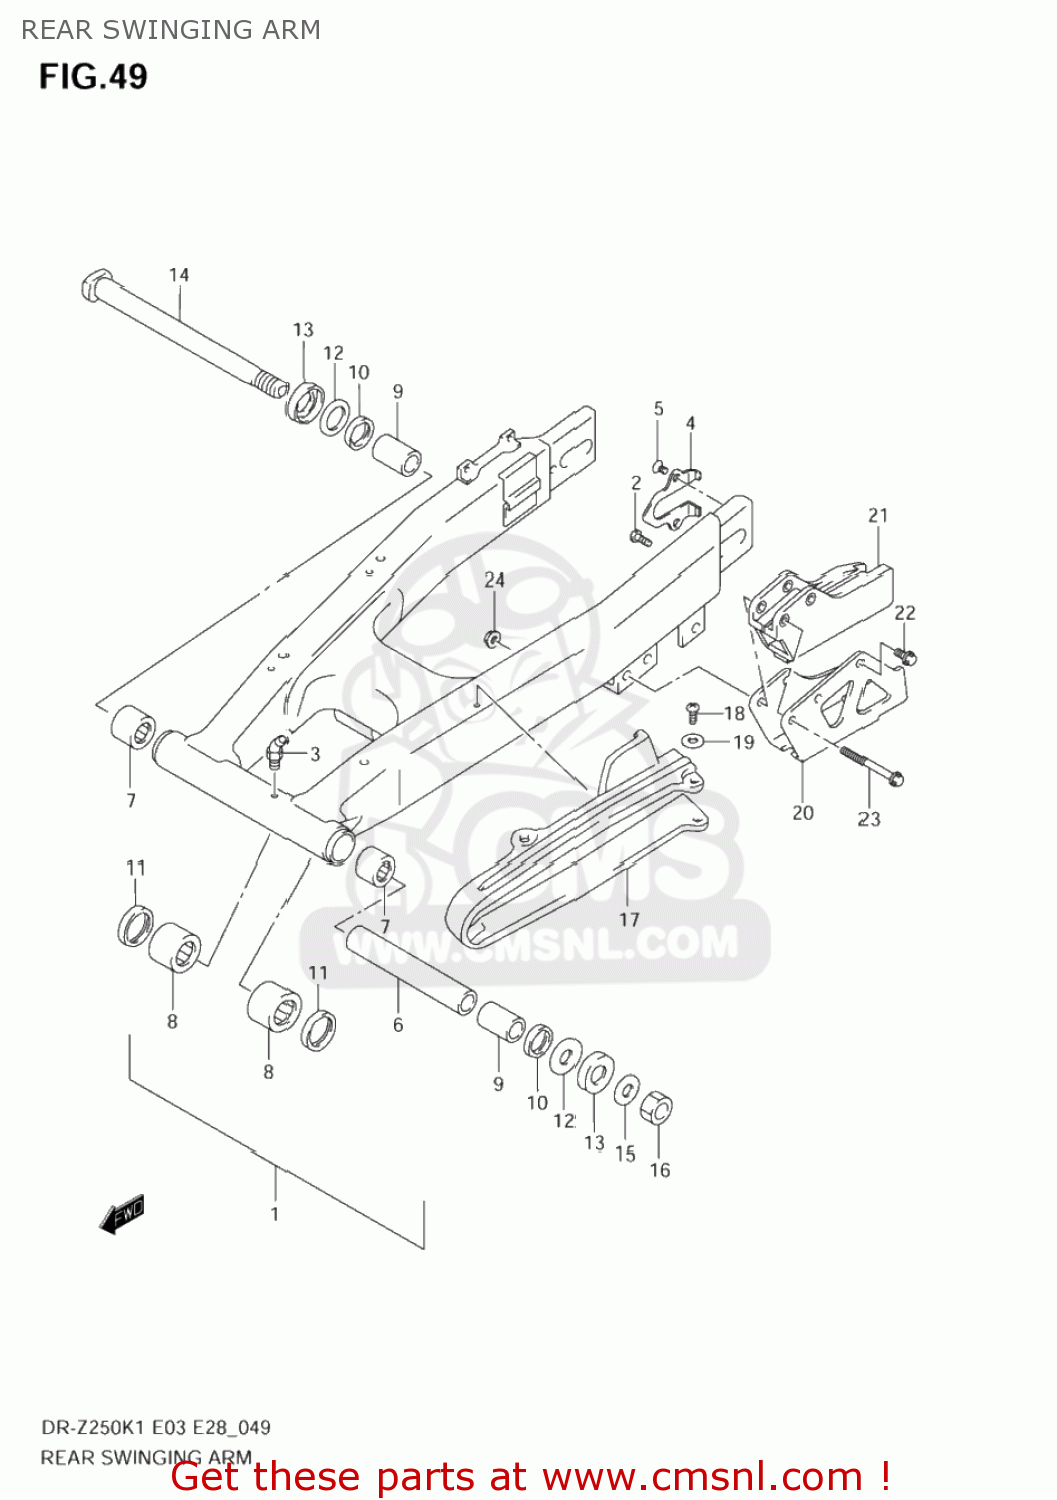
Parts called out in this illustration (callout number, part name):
1	SWINGINGARM ASSY,RR
2	STOPPER,CHAIN ADJUSTER
3	NIPPLE,GREASE
4	PLATE,RR SWING ARM AXLE
5	SCREW(5X8)
6	SPACER,SWGARM PIVOT CTR
7	BEARING(22X29X30)
8	BEARING(20X27X23.5)
9	SPACER,SWGARM PIVOT BRG
10	SEAL,OIL(22X29X4)
11	SEAL,OIL(20X27X5)
12	WASHER
13	COVER,SWINGINGARM PIVOT
14	SHAFT,SWINGING ARM PIVOT
15	WASHER, FIXED DRIVE FACE
16	NUT
17	BUFFER,CHAIN TOUCH DEFENSE
18	SCREW 6X12
19	WASHER
20	PLATE,CHAIN GUIDE
21	GUIDE,CHAIN
22	BOLT
23	BOLT
24	NUT
